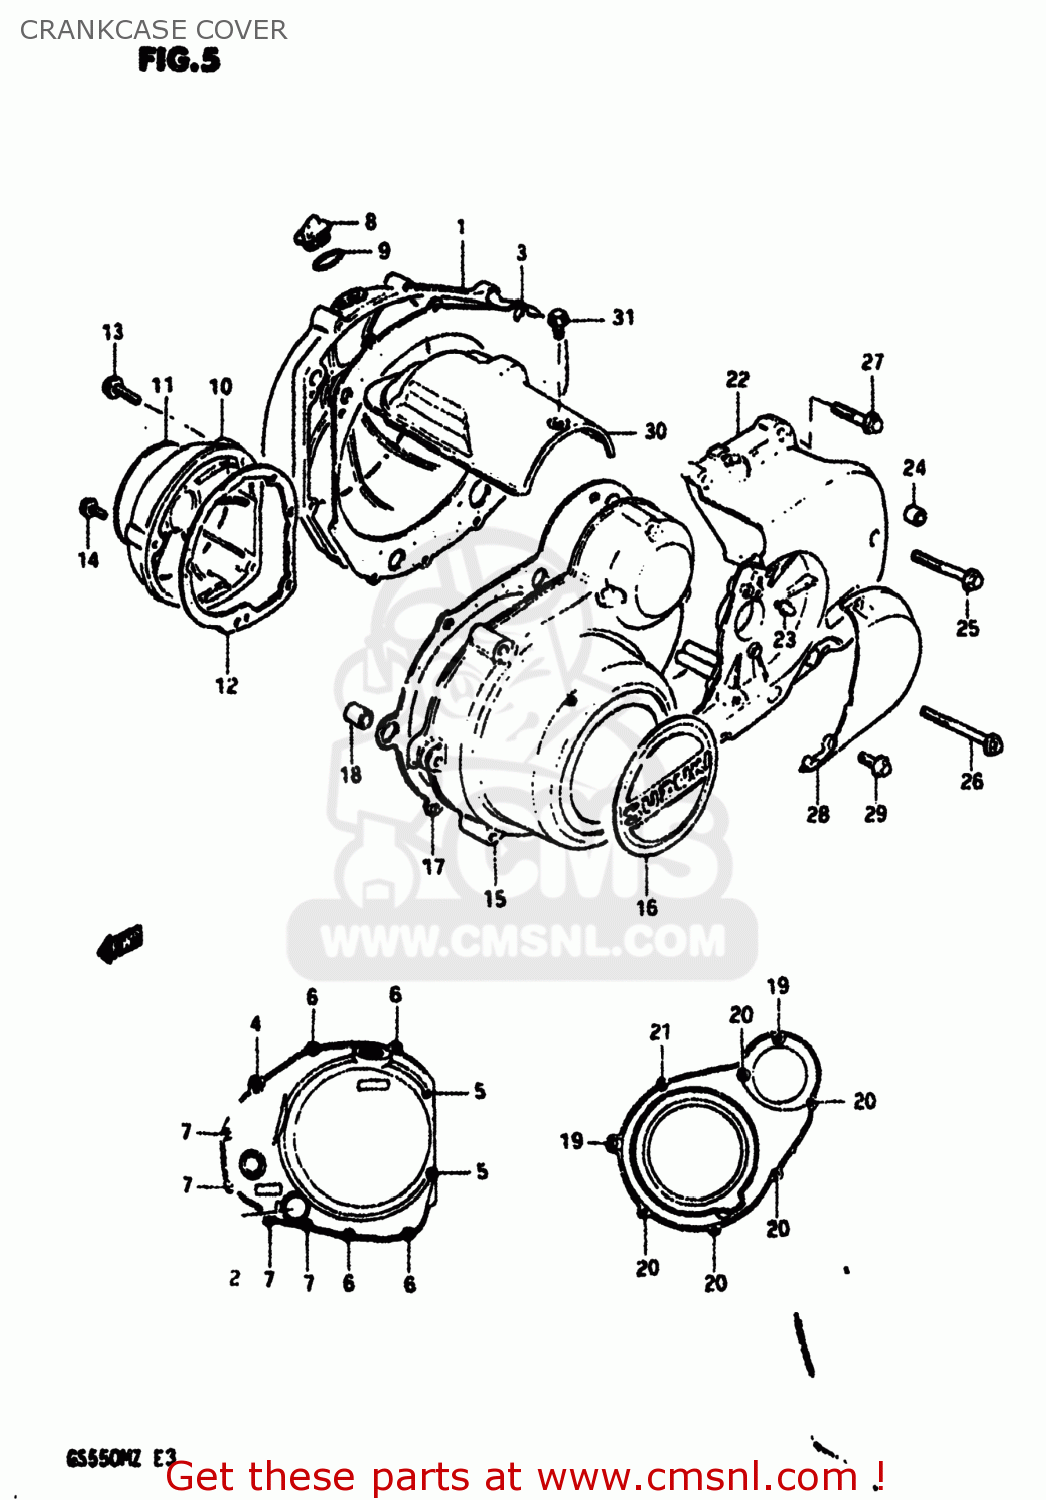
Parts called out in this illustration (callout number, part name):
1	COVER,CLUTCH
2	LENS,OIL LEVEL CHECK
3	GASKET,CLUTCH COVER (MCA)
4	BOLT (6X35)
5	BOLT (6X40)
6	BOLT
7	BOLT (6X20)
8	CAP
9	O RING(D:2.2,ID:32)
10	COVER,CONTACT BREAKER
11	EMBLEM,CONTACT BREAKER COVER
12	GASKET,CONTACT BREAKER COVER (NAS)
13	BOLT (5*30)
14	BOLT 5X16
15	COVER,MAGNETO
16	EMBLEM,MAGNETO COVER
17	GASKET,MAGNETO COVER (MCA)
18	PIN
19	BOLT
20	BOLT (6X40)
21	BOLT (6X35)
22	COVER SET,ENGINE SPROCKET
23	NIPPLE
24	PIN
25	BOLT
26	BOLT
27	BOLT (6X30)
28	CAP,CLUTCH RELEASE ADJUST
29	BOLT 5X16
30	COVER,STARTER MOTOR
31	BOLT (5*8)
